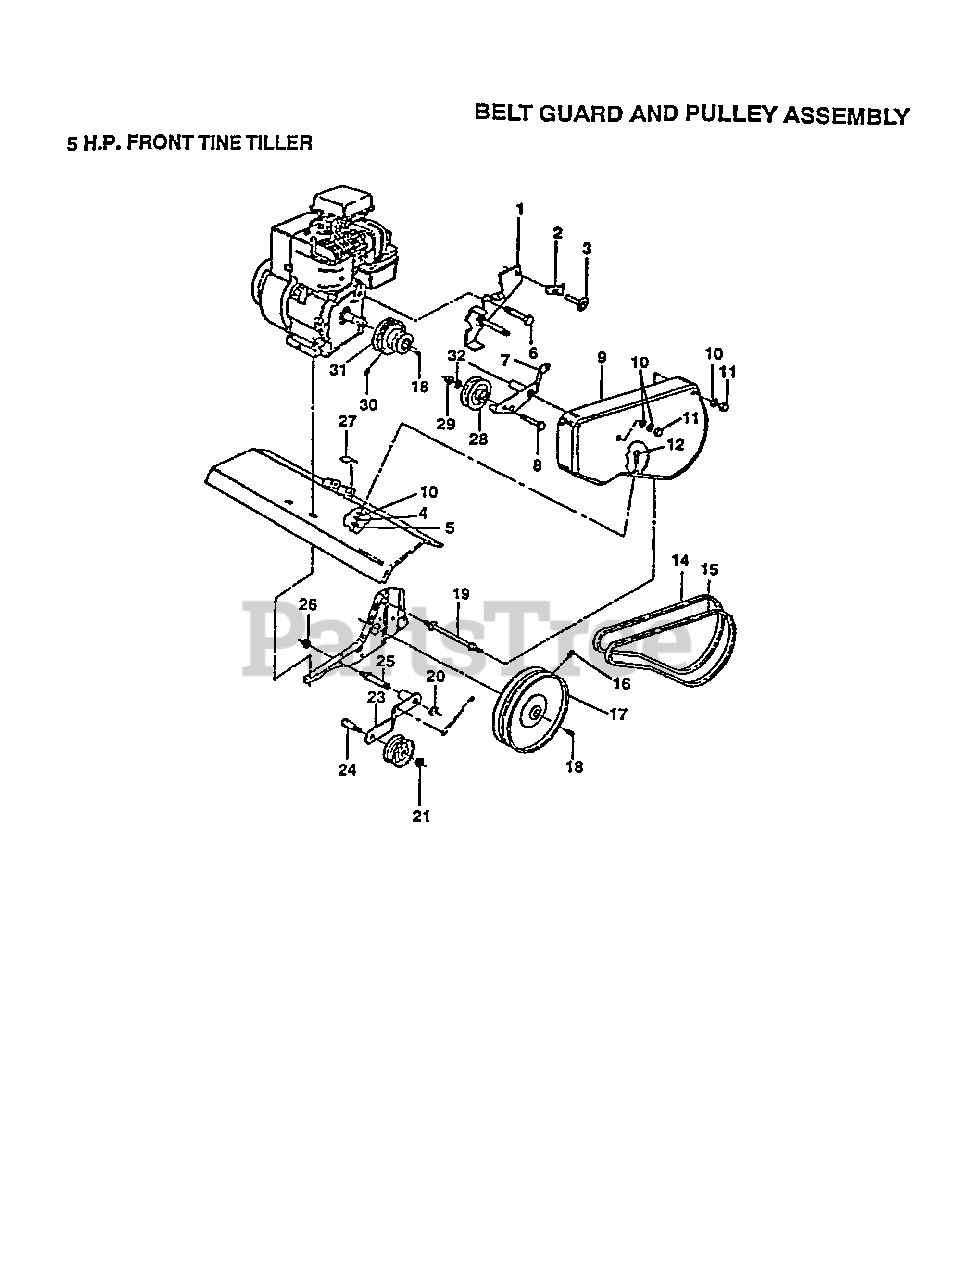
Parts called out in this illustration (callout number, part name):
2	CONDIUT CLIP T
4	LOCKWASHER
7	REV IDLER ARM TI
9	BELT GUARD TI
10	WASHER
11	NUT-CAP TI
12	BOLT T
16	SET SCREW
18	KEY T
19	BOLT TI
20	KLIP RING TI
21	NUT
23	IDLER ARM TI
25	SHAFT IDLER TI
26	JAM NUT TI
27	PAD IDLER TI
28	PULLEY W/SPACER
29	NUT.HEX.3/8-16UNC
30	SET SCREW
31	ENGINE PULLEY TI
32	WASHER
